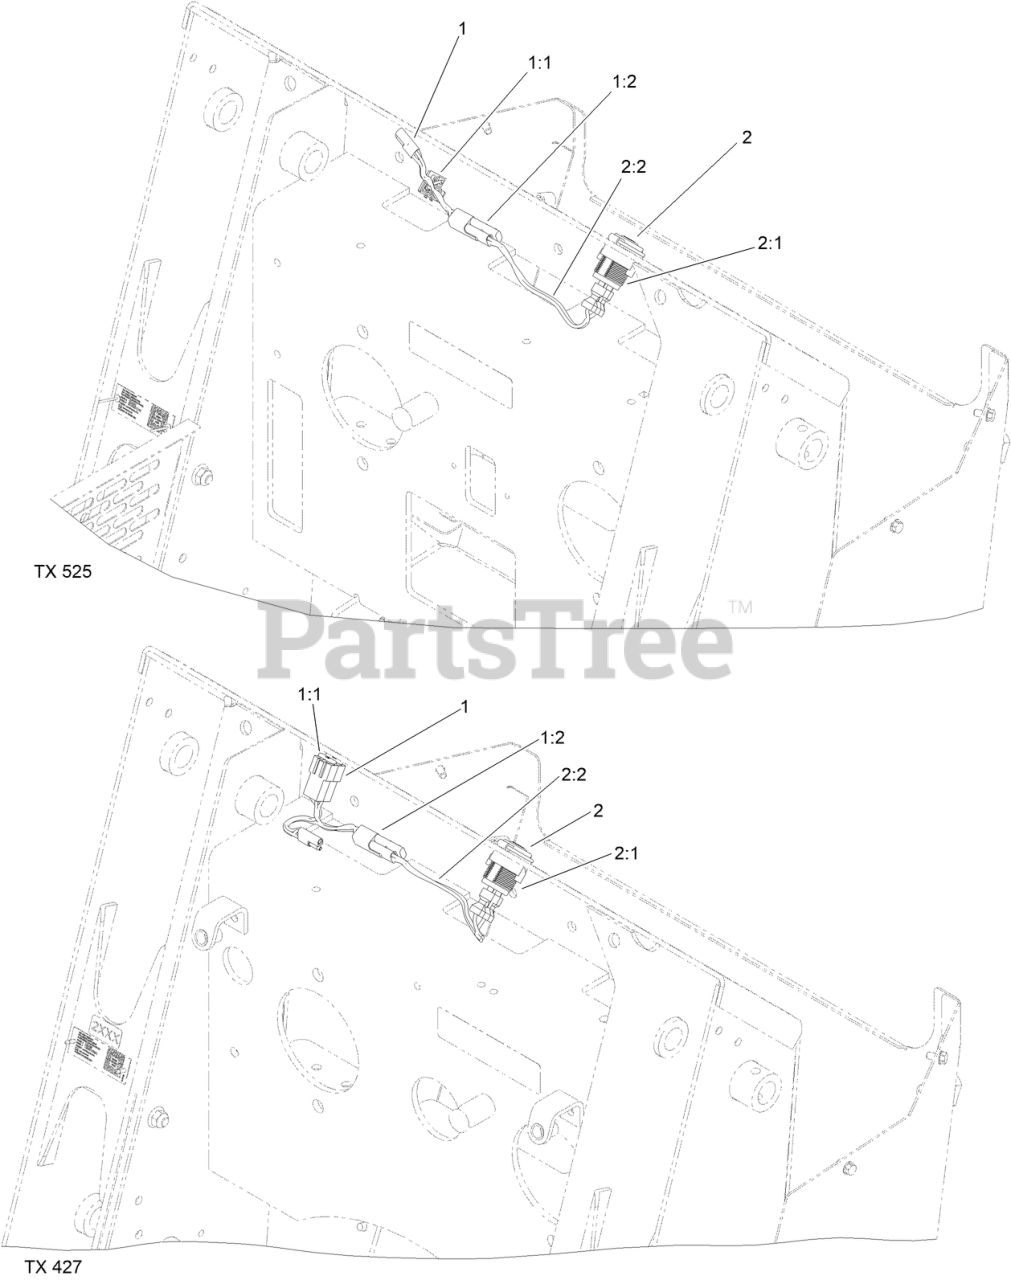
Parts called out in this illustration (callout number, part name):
1	HARNESS-WIRE, SPLITTER
1:1	FUSE-BLADE, 10 AMP
1:2	CAP-PLUG
2	ELEC ACCESSORY PORT, GRANDSTAND MOWER
2:1	RECEPTACLE-12V
2:2	HARNESS, RECEPTACLE 12V
